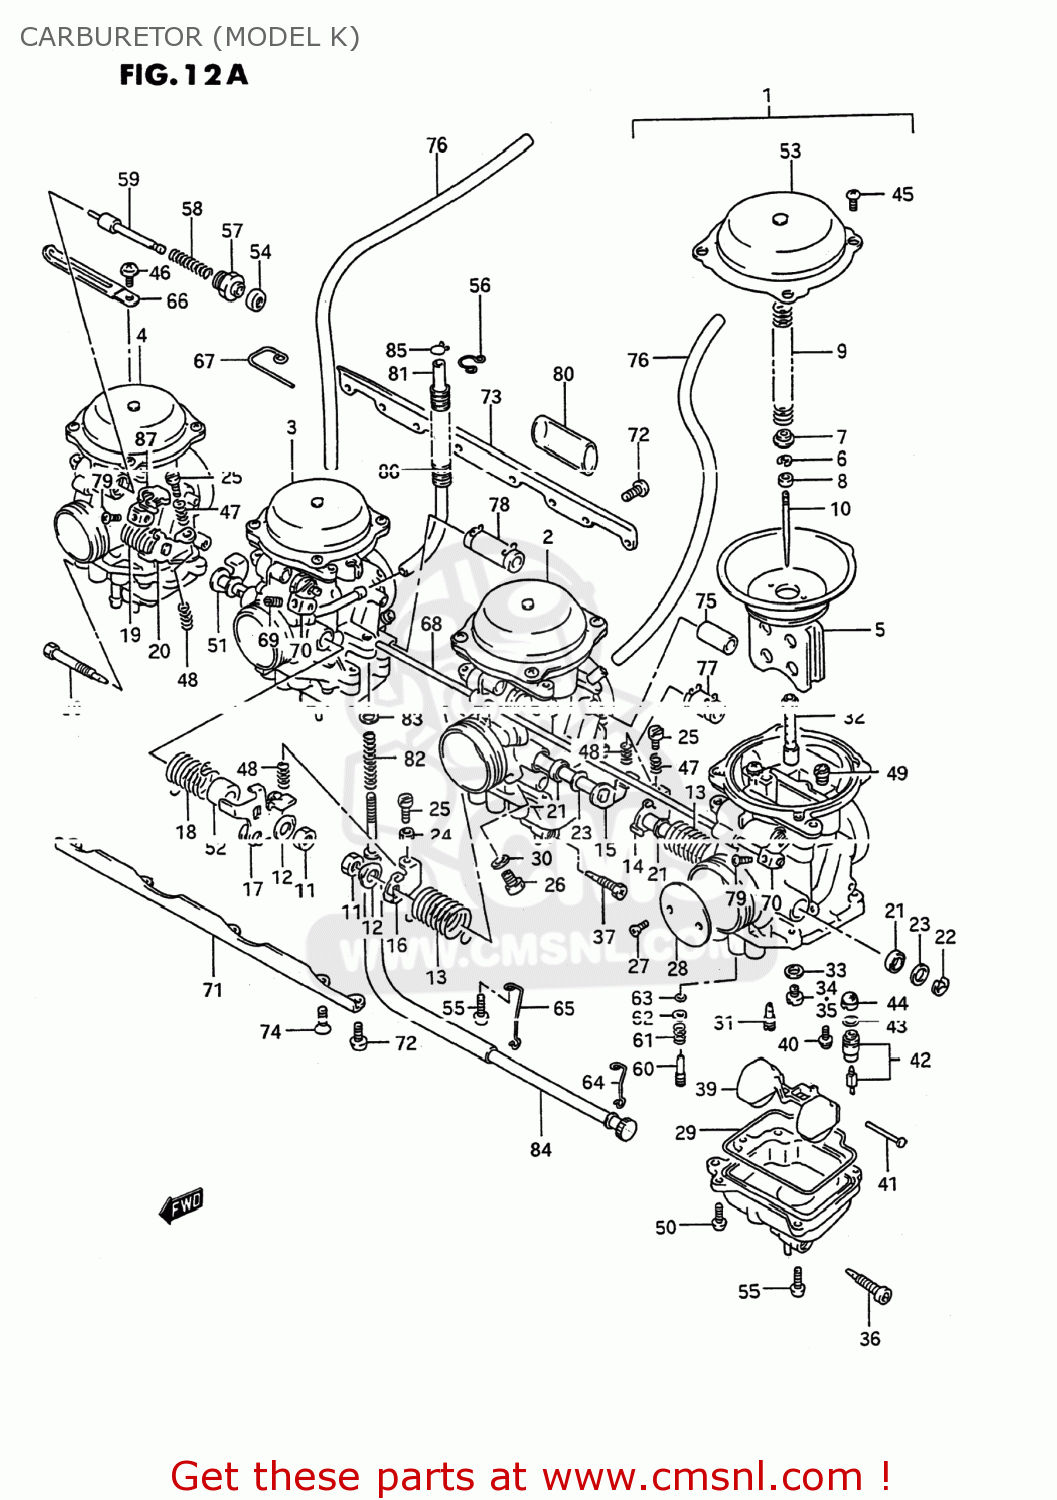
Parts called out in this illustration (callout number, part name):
1	CARBURETOR ASSY,LH
2	CARBURETOR ASS
3	CARBURETOR ASSY,MR
4	CARBURETOR ASS
5	DIAPHRAGM ASSY
6	CLIP
7	RING
8	RING
9	SPRING
10	NEEDLE,JET
11	NUT
12	WASHER
13	SPRING
14	SHAFT ASSEMBLY
15	SHAFT ASSEMBLY
16	LEVER
17	LEVER ASSEMBLY
18	SPRING
19	SPRING
20	SHAFT ASSEMBLY
21	SEAL
22	E RING
23	GASKET,THROTTLE SHAFT (NAS)
24	NUT,THROTTLE ROD
25	SCREW
26	SCREW
27	SCREW
28	VALVE,THROTTLE (130)
29	O RING,FLOAT CHAMBER
30	WASHER
31	JET(40)
32	JET,NEEDLE (P-9)
33	WASHER,NEEDLE NOZZLE
34	JET,MAIN(137.5)
35	JET,MAIN(135)
36	PLUG,DRAIN
37	PLUG
38	SCREW,DRAIN
39	FLOAT
40	SCREW
41	PIN,FLOAT
42	VALVE ASSY,NEEDLE
43	O-RING,NEEDLE VALVE
44	FILTER
45	SCREW
46	SCREW
47	SPRING
48	SPRING,THROTTLE SCREW
49	JET
50	SCREW
51	SHAFT ASSEMBLY
52	RING
53	COVER,DIAPHRAGM
54	CAP,STARTER VALVE
55	SCREW
56	CLIP
57	GUIDE SCREW,PLUNGER
58	SPRING
59	PLUNGER ASSY
60	SCREW,PILOT
61	SPRING
62	WASHER
63	O RING,PILOT AIR SCREW
64	CLIP
65	CLIP
66	CLIP
67	CLIP
68	SHAFT,STARTER
69	SCREW
70	LEVER
71	PLATE
72	SCREW
73	PLATE
74	SCREW(5X14)
75	HOSE,CARBURETOR
76	HOSE
77	HOSE SET (3X5X18)
78	HOSE ASSY
79	SCREW
80	HOSE(16X19X100)
81	HOSE
82	SPRING
83	WASHER
84	ADJUSTER
85	CLIP
86	HOSE
87	LEVER
